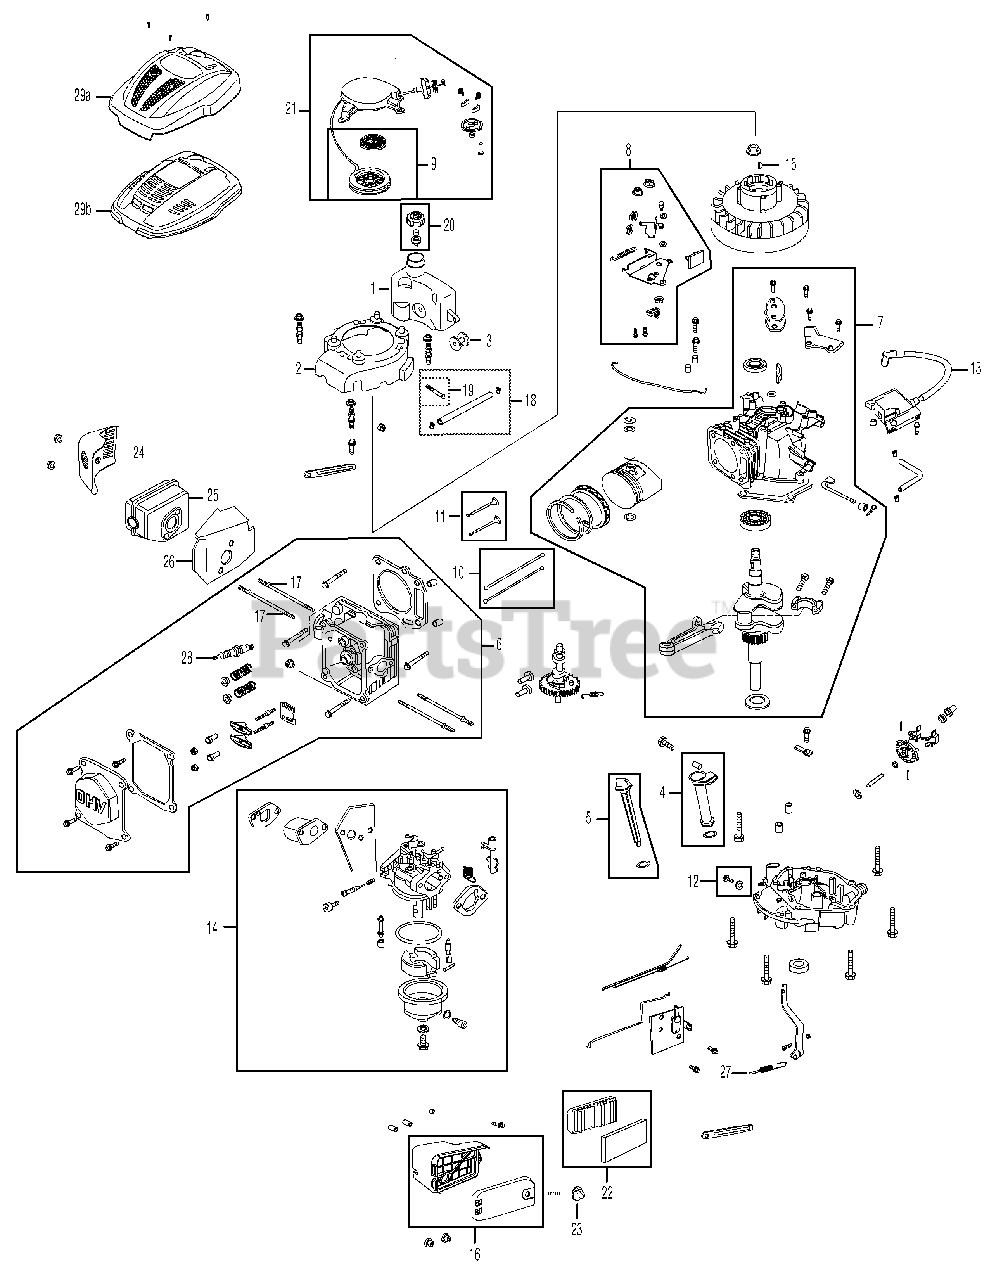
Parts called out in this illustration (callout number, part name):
1	Fuel Tank
2	Flywheel Shroud
3	Rubber Fuel Tank Mounting Washer
4	Oil Filler Tube Assembly
5	Dipstick Assembly
6	Cylinder Head Complete
7	Short Block Assembly
8	Stop Switch and Brake Assembly
9	Recoil Spring and Pulley Assembly
10	Push Rod Kit
11	Valve Kit
12	Oil Drain Plug and Washer Assembly
13	Ignition Coil
14	Carburetor Assembly
15	Flywheel Key
16	Air Cleaner Housing Assembly Complete
17	Muffler Stud Assembly
18	Fuel Line Kit - Inc. hoses, clamps & filters
19	Fuel Filter
20	Fuel Cap Assembly
21	Recoil Starter Assembly
22	Air Cleaner Kit
23	Air Cleaner Thumb Screw
24	Muffler Guard
25	Muffler
26	Muffler Gasket & Heat Shield
27	Governor Return Spring
28	Spark Plug
29A	Engine Shroud
29B	Engine Shroud
